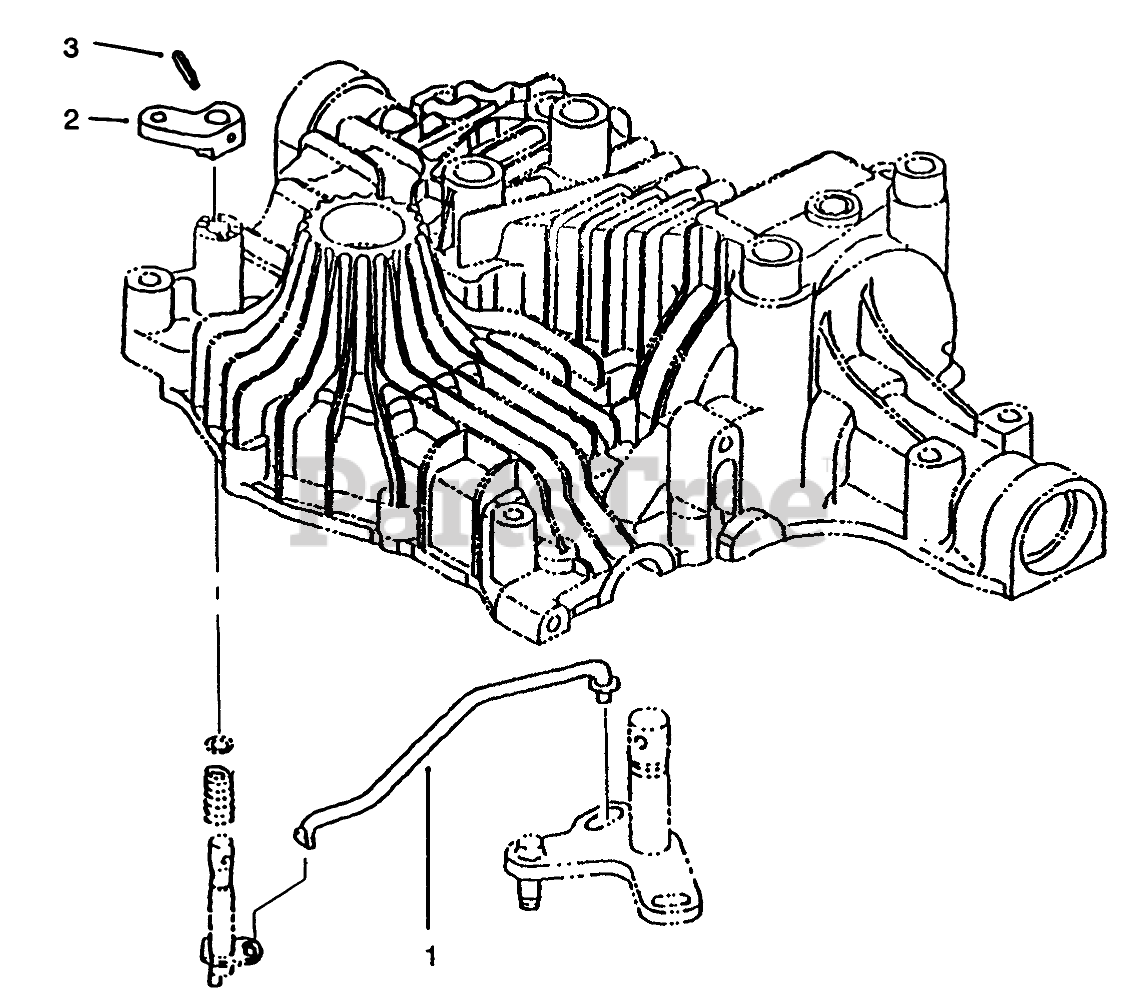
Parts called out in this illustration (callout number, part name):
1	Rod-Bypass (Only On: 72083, 72043, 72103 72063)
2	Arm-Valve Release (Only On: 72083,72043,72103,72063)
3	Pin-Roll (Only On: 72083, 72043, 72103, 72063)
